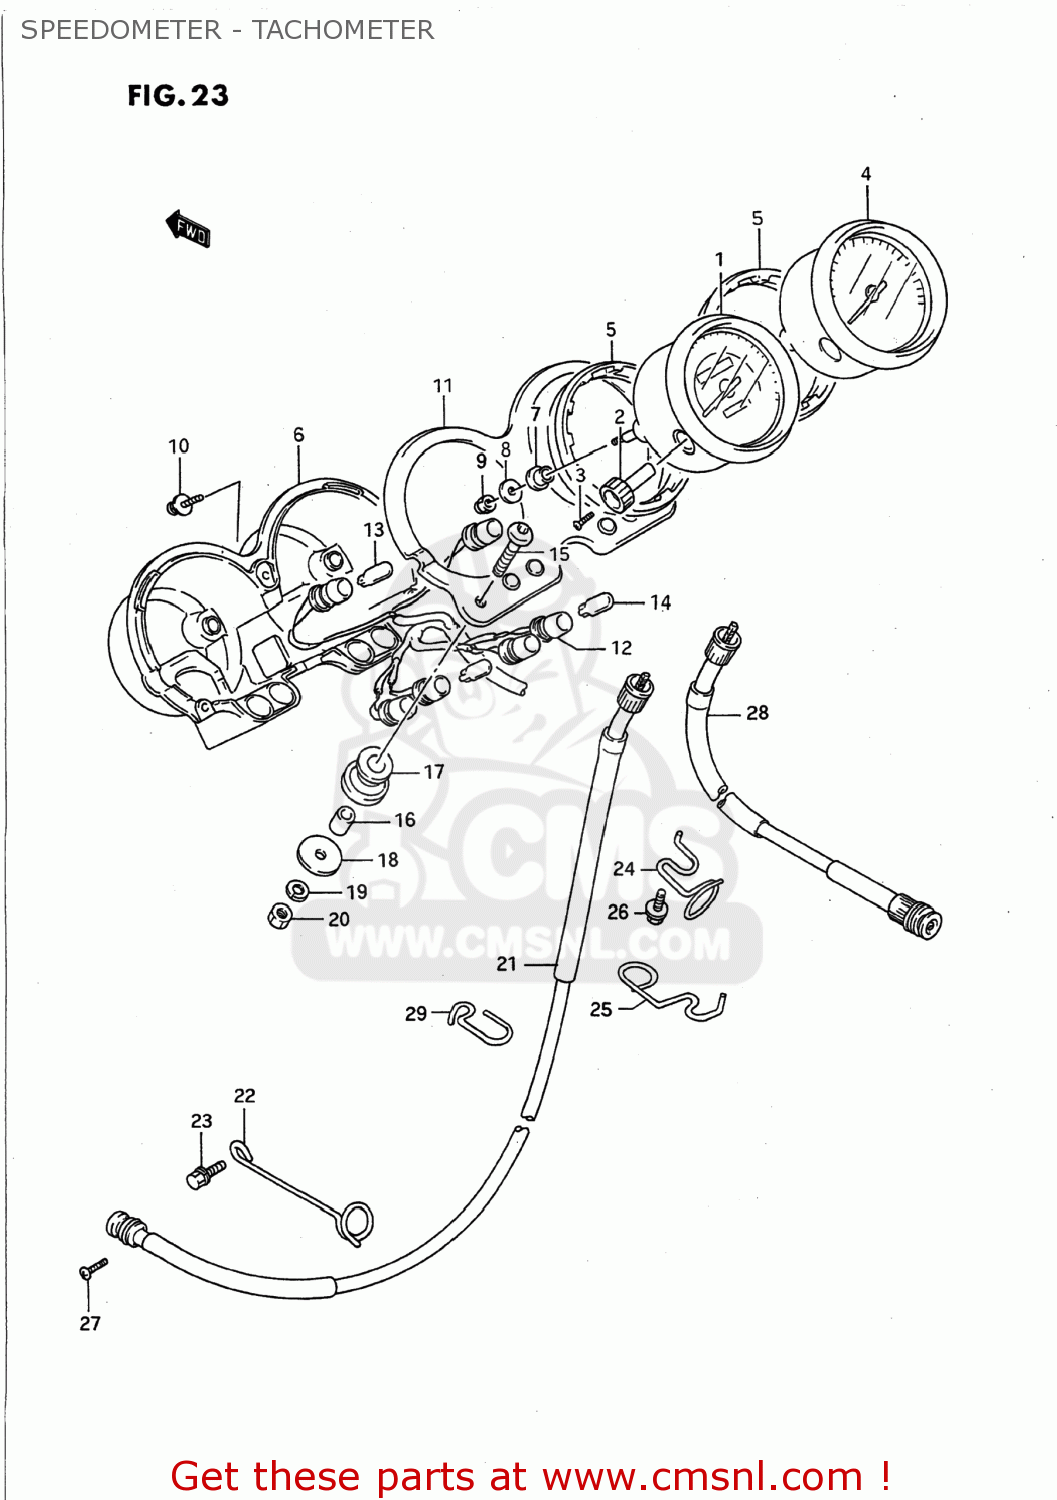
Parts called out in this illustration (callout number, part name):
1	SPEEDOMETER(MILE/KILO)
2	KNOB
3	SCREW(2X6)
4	TACHOMETER
5	DAMPER
6	COVER
7	CUSHION
8	WASHER,METER
9	NUT
10	SCREW
11	BRACKET,METER
12	SOCKET
13	BULB(12V3.4W,T10)
14	BULB(12V1.7W,T10,WB121)
15	BOLT(6X30)
16	SPACER (6.1X10X15.7)
17	CUSHION,METER BRACKET
18	WASHER (6.5X29X1.6)
19	WASHER,LOCK
20	NUT
21	CABLE ASSY,SPEEDOMETER
22	CLAMP,SPEEDOMETER CABLE
23	BOLT
24	GUIDE,SPEEDOMETER CABLE
25	GUIDE,SPEEDOMETER CABLE NO.2
26	BOLT
27	SCREW
28	CABLE ASSY,TACHOMETER
29	GUIDE,SPEEDOMETER CABLE NO.3
